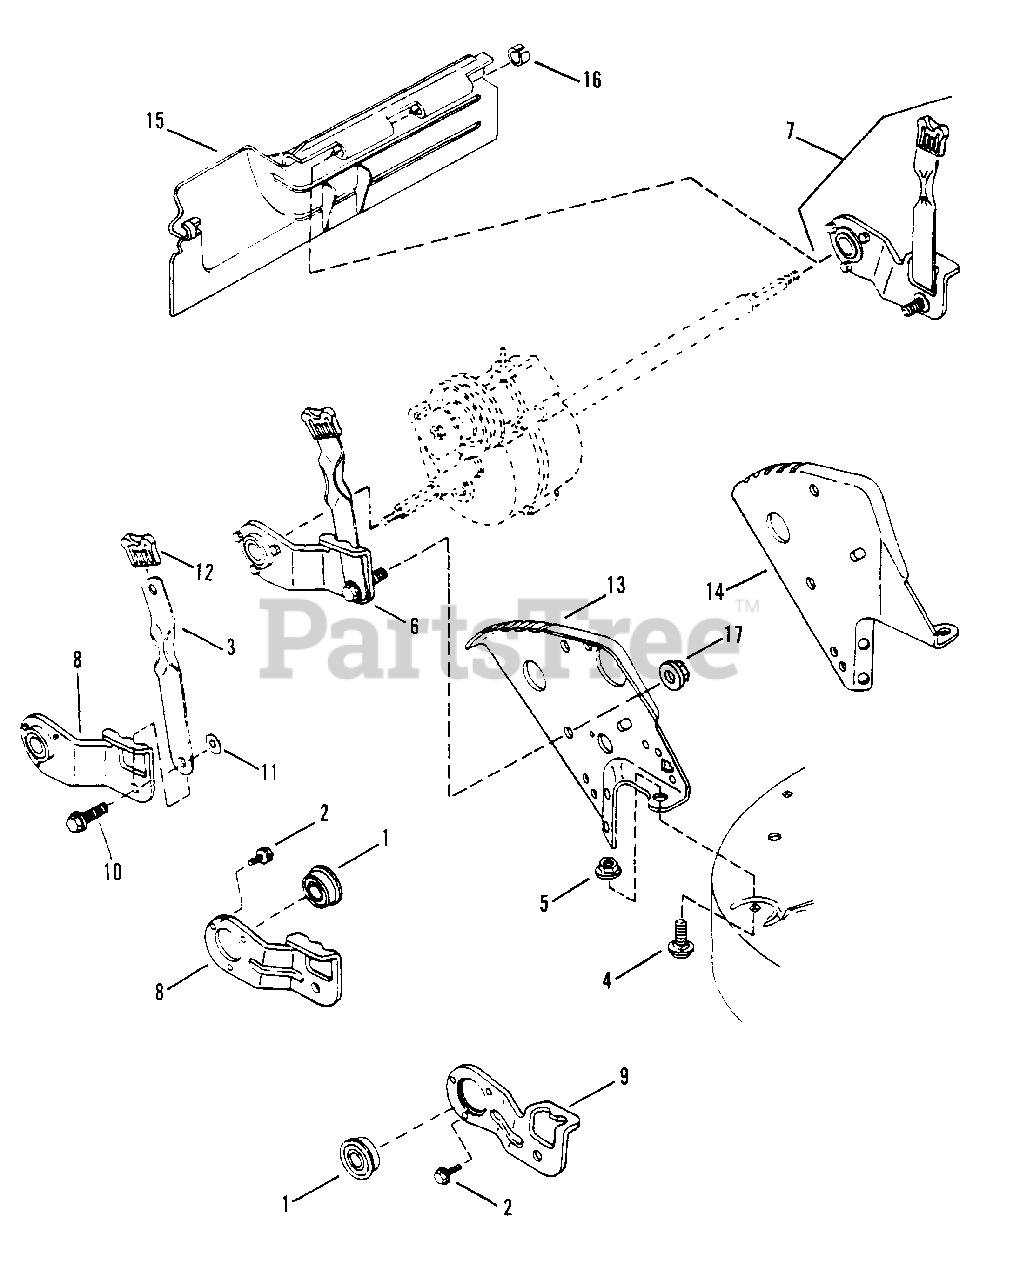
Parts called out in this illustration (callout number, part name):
1	BEARING
2	SCREW, #10-32 x 3/8" Self-Tapping
3	LATCH, Height Adjusting (Long)
4	BOLT, 5/16-18 x 3/4" Short Neck Carriage
5	NUT, 5/16-18 Hex Flange Lock
6	ASSEMBLY, Wheel Arm
7	ASSEMBLY, Wheel Arm
8	ARM, Right Rear Wheel
9	ARM, Left Rear Wheel
10	BOLT, 5/16-18 x 3/4" Shoulder
11	RETAINER, 5/16 Bolt
12	GRIP, Latch
13	BRACKET, Right Rear Wheel
14	BRACKET, Left Rear Wheel
15	GUARD, Rear Foot
16	RING, Black
17	NUT, 5/16-18 Hex Flange Lock
